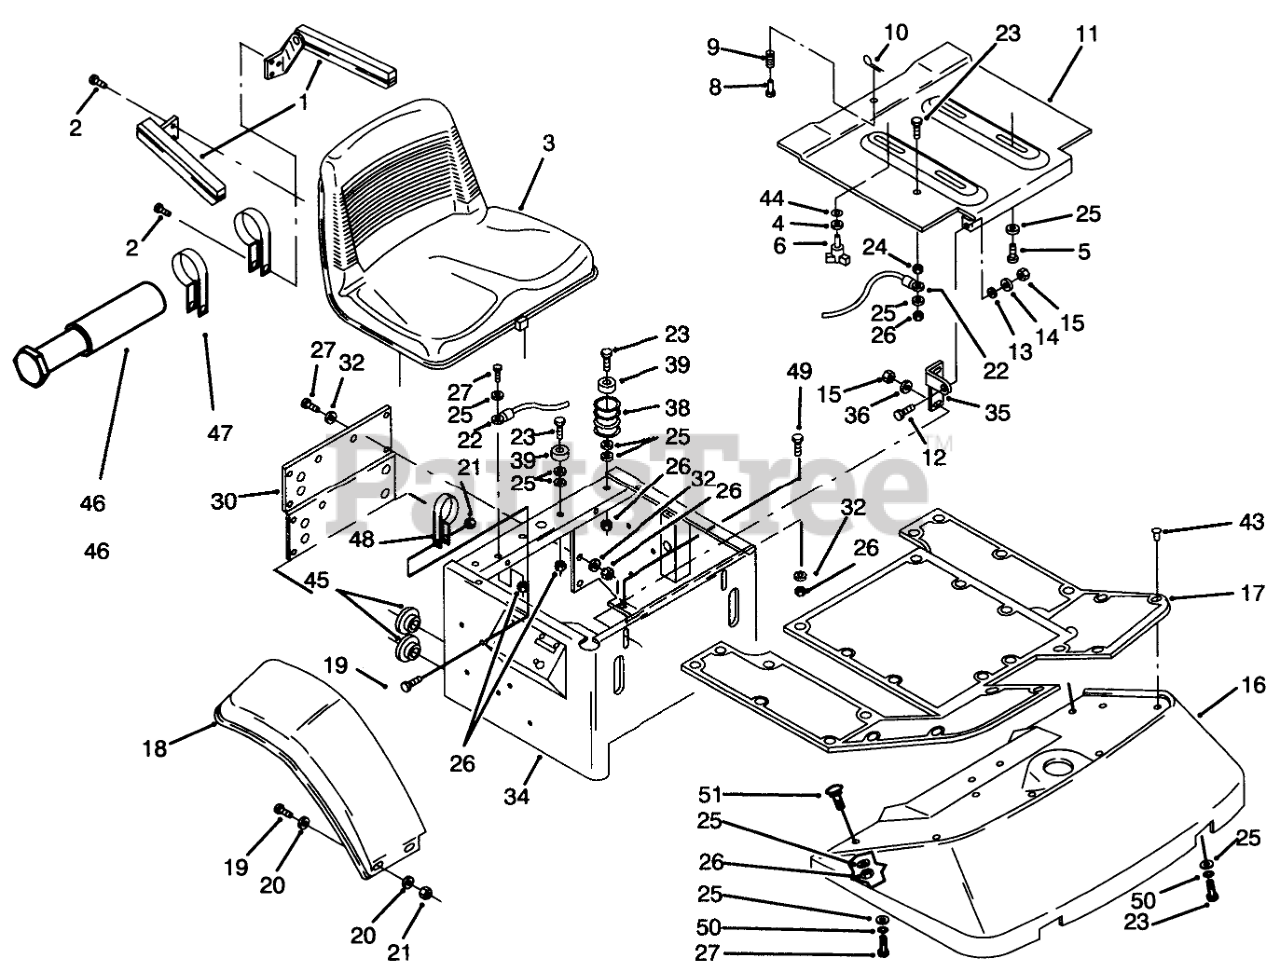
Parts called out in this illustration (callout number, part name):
1	KIT-ARMREST
2	3/8-16 X 5/8 SCREW
3	SEAT V-510
4	WASHER-PLAIN
5	BOLT 5/16-18X5/8
9	SPRING-COMPRESSION
10	PIN-COTTER
11	PLATE SEAT PIVOT R
12	BOLT-CARR
13	SPACER
14	WASHER-FLAT
15	NUT-LOCK, NI
16	Floor Pan
17	Black Mat
18	Fender RH
19	SCREW-HH
20	WASHER-FLAT
21	NUT-LOCK, NI
22	Cable
23	SCREW-HH
24	NUT-HEX
25	WASHER-FLAT
26	NUT-LOCK, NI
27	SCREW-HH
30	Cover
32	WASHER-PLAIN
34	SUPPORT-SEAT W A R
35	Seat Pivot Bracket RH
36	WASHER-FLAT
38	Spring
39	BUMPER
43	RIVET .25 PLASTIC
44	LOCKWASHER INT EXT
45	BUSHING-NYLON 1.500
46	TUBE-MANUAL
47	CLAMP-R
48	CLAMP-R
49	SCREW-HHF
50	WASHER-LOCK
51	BOLT-CARR
